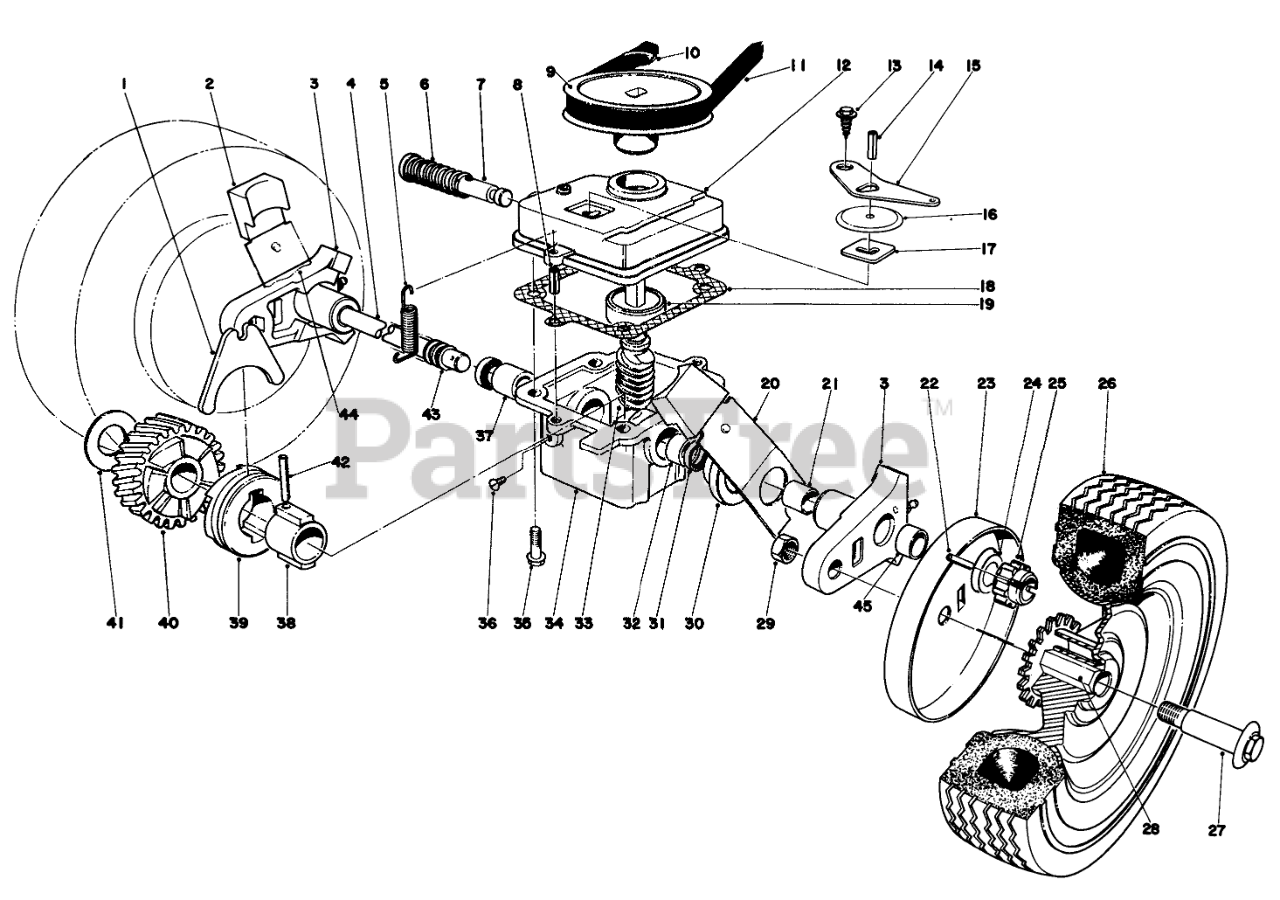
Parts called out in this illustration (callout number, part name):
1	SHIFTER FORK
2	KNOB-ARM
3	Pivot Arm (Incl.Ref. #21 & 45)
4	Drive Shaft
5	TENSION SPRING
6	SPRING
7	Shift Rod
8	3/16 X 1/2 ROLL PIN
9	PULLEY
10	PUSH-ON 93-3236
11	V BELT
12	Cover Gear Case
13	Screw
14	PIN-ROLL
15	SHIFTER ARM
16	TRANS DUST COVER
17	LATCH PLATE
18	GASKET
19	Bearing
20	SPRING ARM ASM SP LH
21	BUSHING
22	Pin
23	WHEEL COVER
24	WASHER-THRUST
25	Pinion
26	Wheel & Tire Assembly (Incl. Ref. #28)
28	WHEEL BUSHING
29	Nut
30	End Cap
31	Seal
32	Bushing
33	Worm Shaft & Gear (Incl. Ref. #40)
34	Gear Case (Incl. Ref. #31, 32 & 37)
35	Screw
36	NYLON SCREW
37	Bushing
38	SLEEVE
39	CLUTCH JAW
40	Helical Gear
41	THRUST WASHER
42	COIL PIN
43	COVER-SHAFT, DRIVE
44	SPRING ARM ASM SP RH
45	BUSHING
